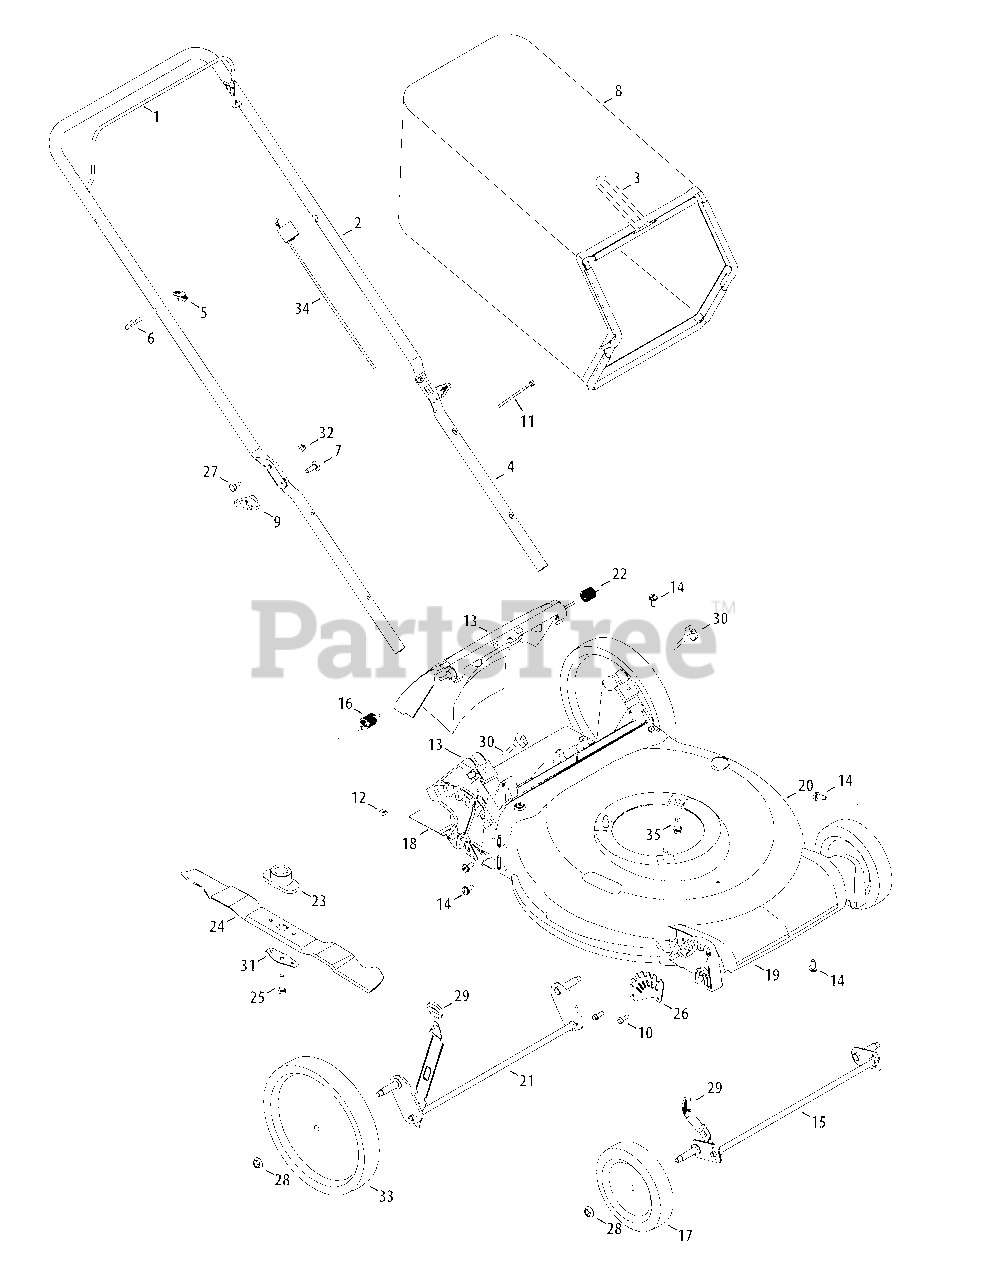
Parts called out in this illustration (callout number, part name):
1	Blade Control
2	Upper Handle
3	Grass Catcher Frame
4	Lower Handle
5	Wing Nut
6	Rope Guide
7	Carriage Screw, 5/16-18
8	Grass Bag
9	Wing Knob
10	Screw, 1/4-15 x .750
11	Cable Tie
12	Nut, Sq., 1/4-20
13	Rear Discharge Door Assembly
14	Screw, 5/16-14 x .750
15	Front Axle Assembly
16	Torsion Spring - RH
17	Front Wheel Gray
18	Trail Shield
19	Front Cover
20	Deck - 21"
21	Rear Axle Assembly
22	Torsion Spring - LH
23	Blade Adapter
24	Mulching Blade
25	Screw , 3/8-24 x 1.50
26	Front Height Adjuster Plate
27	Sldr. Screw, .375 x .126 x 1/4-20
28	Flange Lock Nut, 3/8-16
29	Adjustment Lever Knob
30	Wing Nut
31	Blade Bell Support
32	Nut, Flange Lock, 1/4-20
33	Rear Wheel
34	Control Cable
35	TT Sems Screw, 3/8-16 x 1.0
